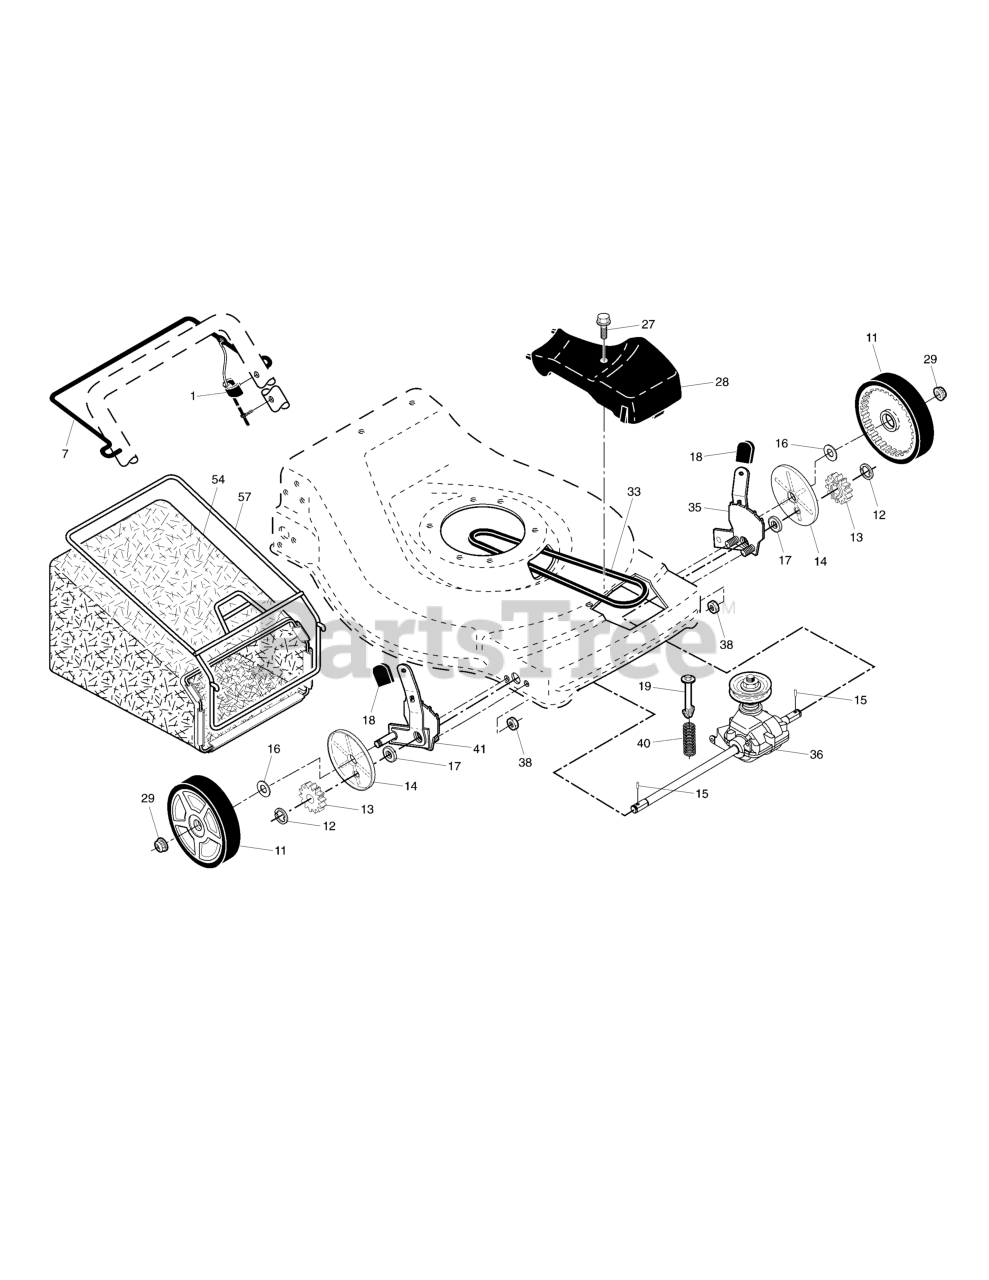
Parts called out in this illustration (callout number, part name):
1	Cable, Drive Control
7	Bar, Drive Control
11	Wheel & Tire Assembly, Front
12	E-Ring
13	Pinion
14	Dust Cover
15	Pawl, Drive
16	Washer, Flat 3/8
17	Bearing, Wheel Adjuster
18	Selector Knob
19	Spring Retainer
27	Pan Head Tapping Screw #10-24 x 2-3/4
28	Drive Cover
29	Locknut, Hex
33	V-Belt
35	Kit, Wheel Adjuster, LH (Includes Knob & Bearing)
36	Gear Case Assembly, Complete
38	Locknut, Hex 1/4-20
40	Spring
41	Kit, Wheel Adjuster, RH (Includes Knob & Bearing)
54	Grassbag Assembly
57	Frame, Grassbag
